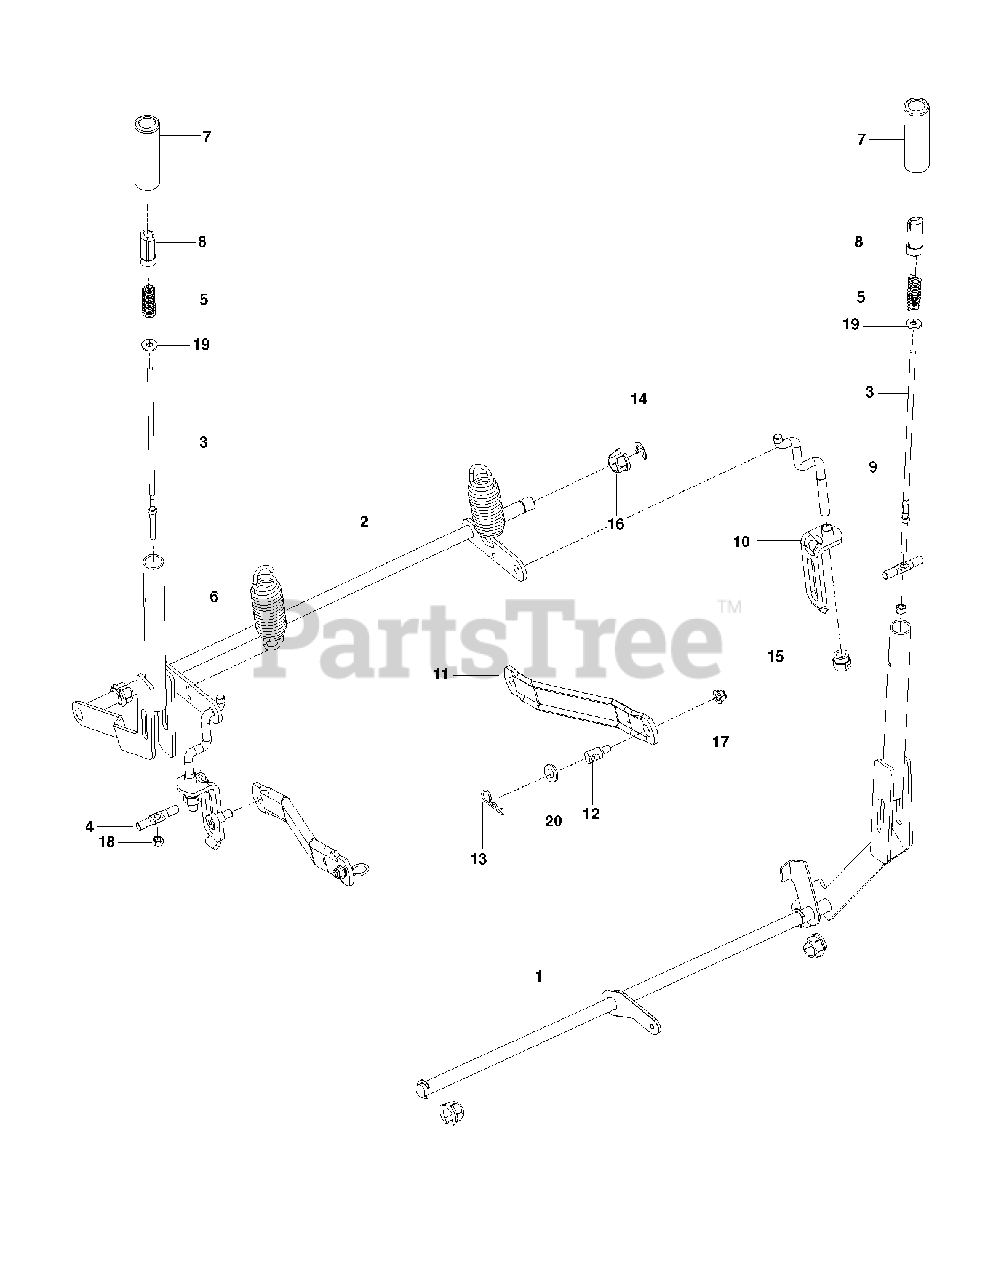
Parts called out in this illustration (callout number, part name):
1	SHAFT.ASSY.BRAKE.WLDMT.BLACK
2	SHAFT, LIFT, BLACK
3	ROD, HANDLE RELEASE
4	RB ROD, LATCH RELEASE
5	SPRING, COMPRESSION
7	GRIP, HANDLE, BLACK 4"
8	BUTTON, PUSH, BLACK
9	LINK, REAR SUSPENSION
10	ASSEMBLY, BRKT LINK
11	ARM.SUSPENSION.MOWER
12	STUD.FASTNER.W/ANTI-ROTATE
13	HAIRPIN #4
14	E-RING 5/8
15	NUT, LIFT LINK 7/16-20
16	PLASTIC NUT
17	5/16-18 NYLOC FLANGE NUT
18	LOCKNUT.NYLOC.1/4-20
20	WASHER
